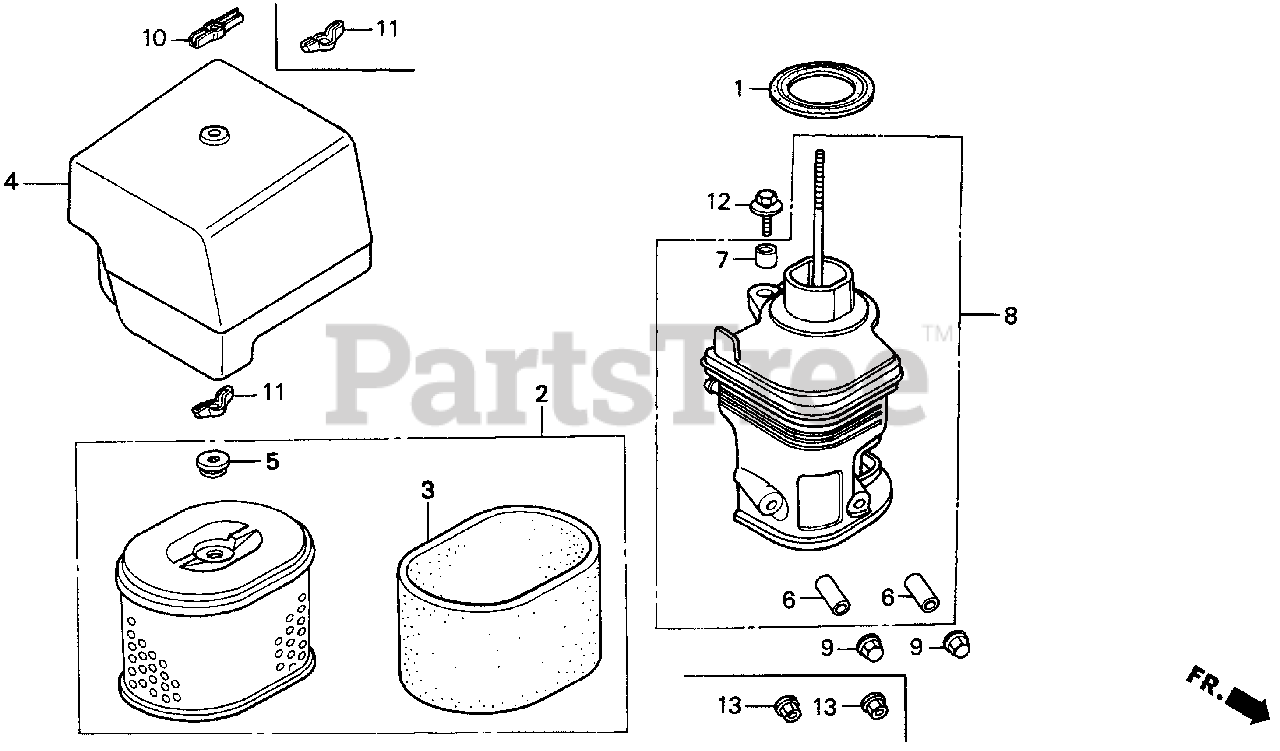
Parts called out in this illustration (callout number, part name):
1	GASKET, ELBOW
2	ELEMENT, AIR CLEANER (DUAL)
3	FILTER (OUTER)
4	COVER, AIR CLEANER
5	GROMMET, AIR CLEANER
6	COLLAR, AIR CLEANER
7	COLLAR B, AIR CLEANER
8	ELBOW, AIR CLEANER
9	NUT, CAP (6MM)
10	WINGNUT, AIR CLEANER COVER
10	WINGNUT (6MM)
11	WINGNUT, TOOL BOX SETTING
12	BOLT-WASHER (6X20)
